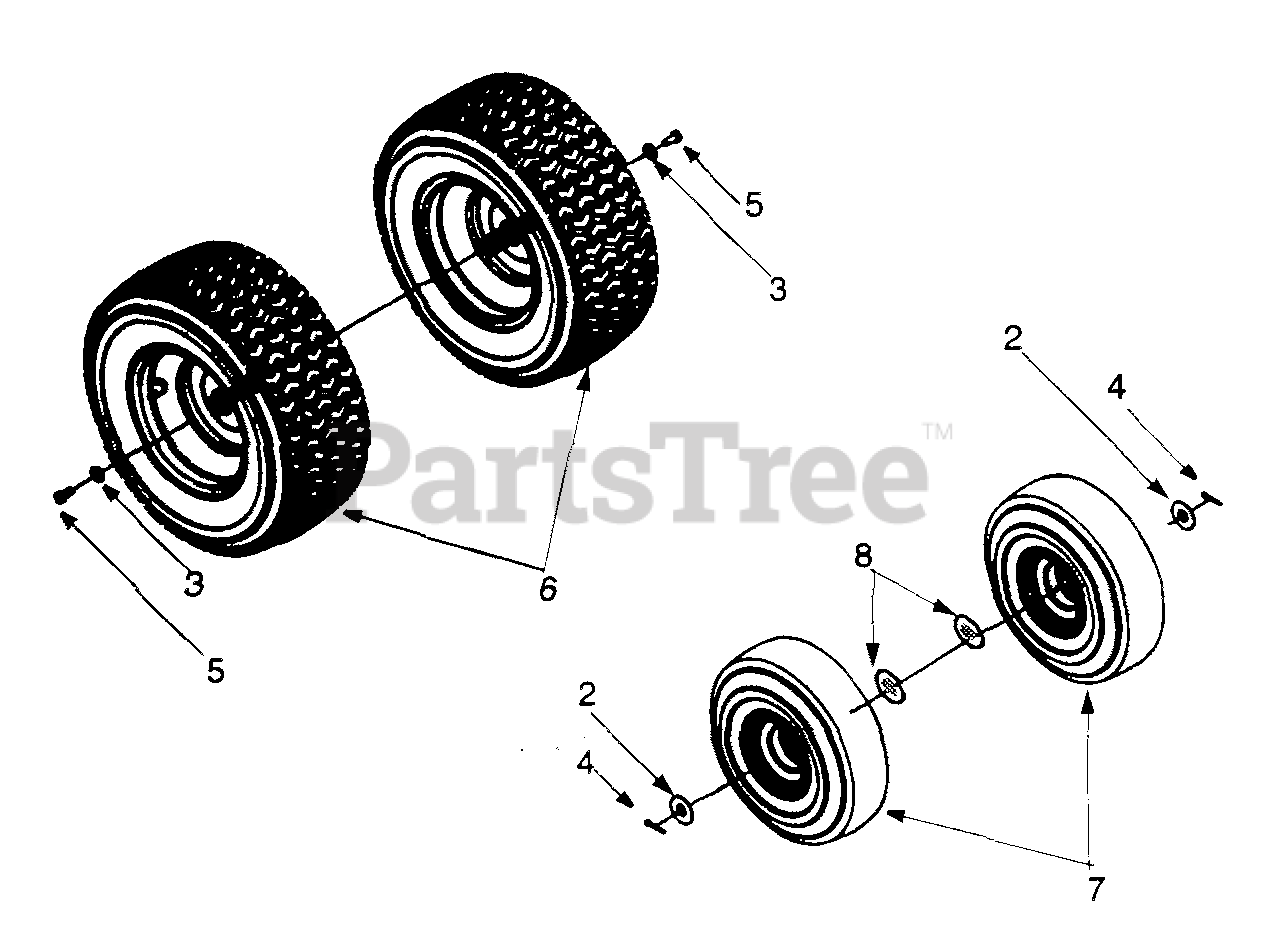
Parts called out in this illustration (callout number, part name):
2	Flat Washer .635 x 1.589 x .060
3	Bell Washer .345 I.D. x .88 O.D. x .06
4	Hairpin Clip
5	Hex Screw 5/16-24 x .75
